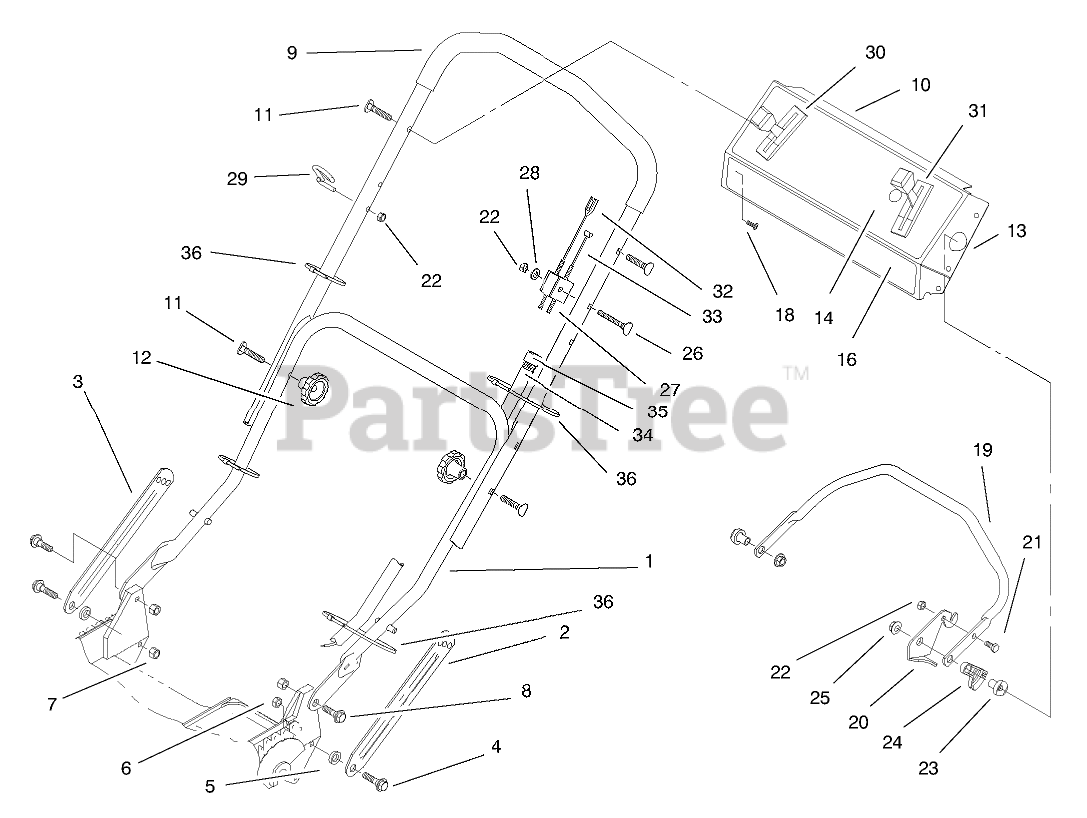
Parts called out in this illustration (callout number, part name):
1	ASM-Handle
2	Latch-Handle
3	Latch-Handle
4	SCREW-SHOULDER
5	SPACER
6	NUT-LOCK, NI
7	NUT-LOCK, NI
8	SCREW-SHOULDER
9	HANDLE - DIPPED
10	DECAL-PANEL, REAR
11	SCREW-HANDLE
13	PANEL ASM (SERVICE)
14	DECAL - INSTRUCTION
16	DECAL - PANEL
18	SCREW-TAP
19	Bar-Control
20	Lever-Control
21	SCREW-HH
22	NUT-LOCK, NI
23	SPACER-SUPPORT
24	LEVER-TRACTION
25	NUT-LOCK NI
26	SCREW-HANDLE
27	SUPPORT-CABLE
28	WASHER-FLAT
29	GUIDE-ROPE
30	CONTROL-SPEED, GROUND
31	CABLE - THROTTLE
32	CABLE - BRAKE
33	CABLE-TRACTION
34	CONTROL CABLE COVER
35	FITTING-RING
36	TIE-CABLE
